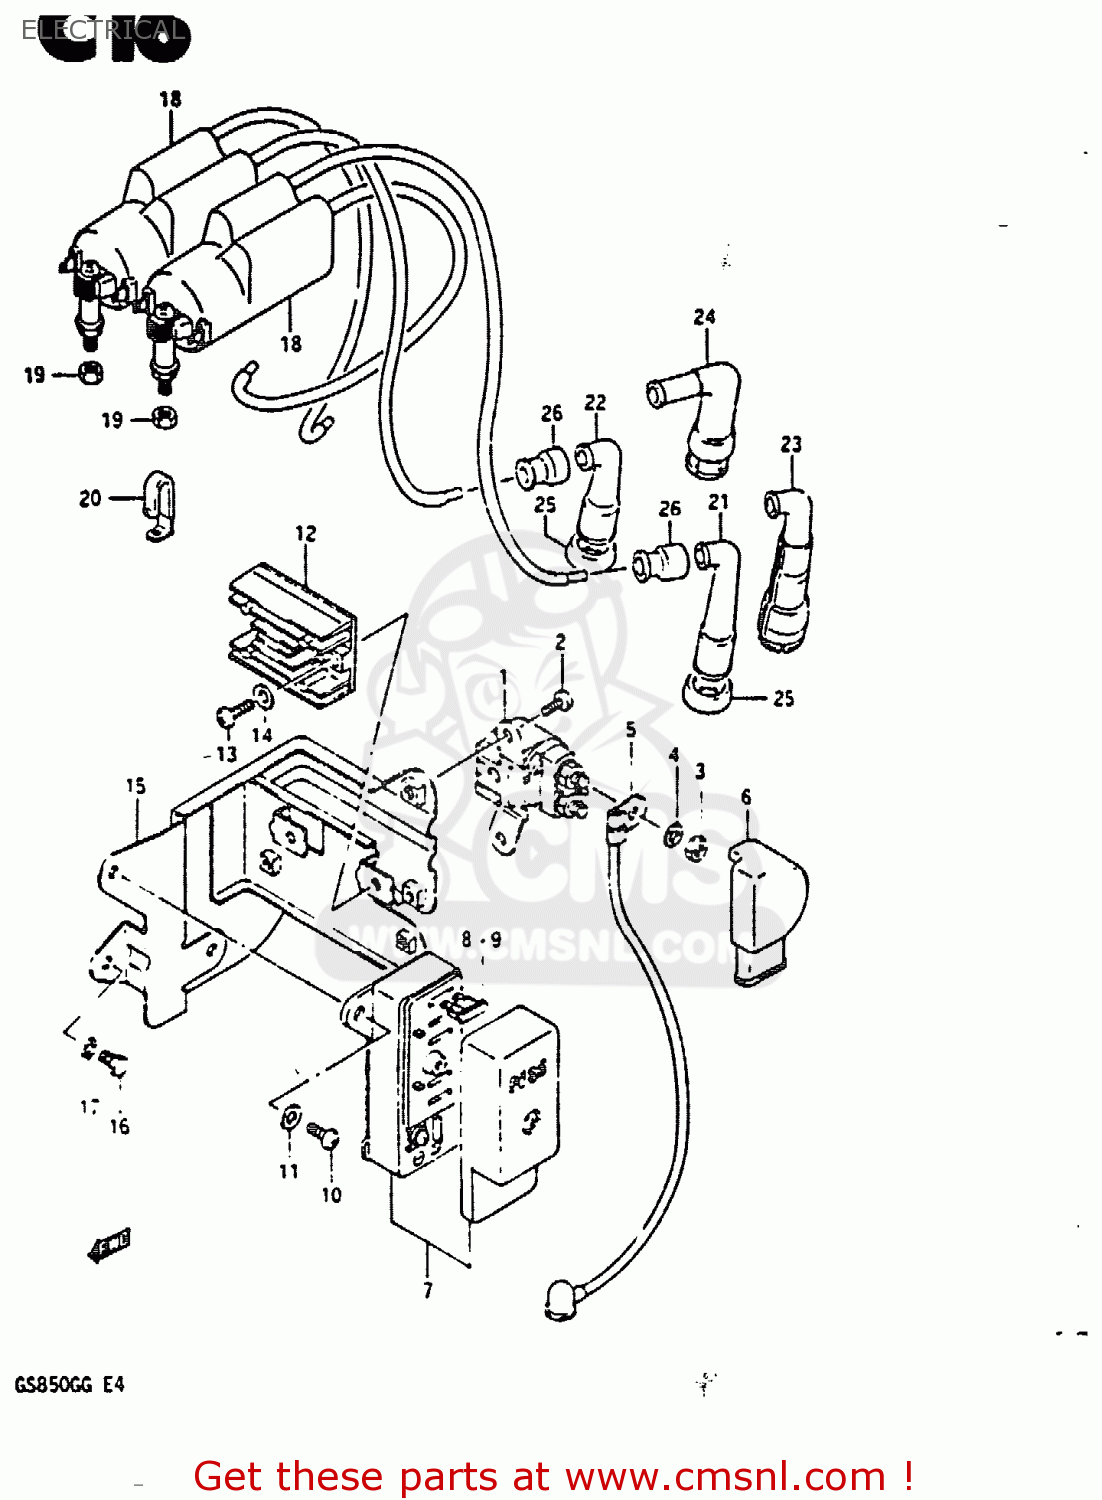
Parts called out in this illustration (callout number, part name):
1	RELAY ASSY,STARTING MOTOR
2	SCREW
3	NUT
4	WASHER,LOCK
5	WIRE,STARTER MOTOR LEAD
6	CAP,STARTER RELAY TERMINAL
7	BOX ASSEMBLY,FUSE
8	FUSE(10A)
9	FUSE(15A)
10	SCREW
11	WASHER, LOWER
12	RECTIFIER ASSEMBLY
13	SCREW
14	WASHER
15	HOLDER COMP,ELECTRONIC PARTS
16	BOLT
17	WASHER,LOCK
18	COIL ASSEMBLY,IGNITION
19	NUT 6MM
20	CLAMP
21	CAP ASSY,SPARK PLUG
22	CAP,SPARK PLUG
23	CAP,SPARK PLUG
24	CAP, SPARK PLUG (S)
25	SEAL,SPARK PLUG
26	SEAL,SPARK PLU
